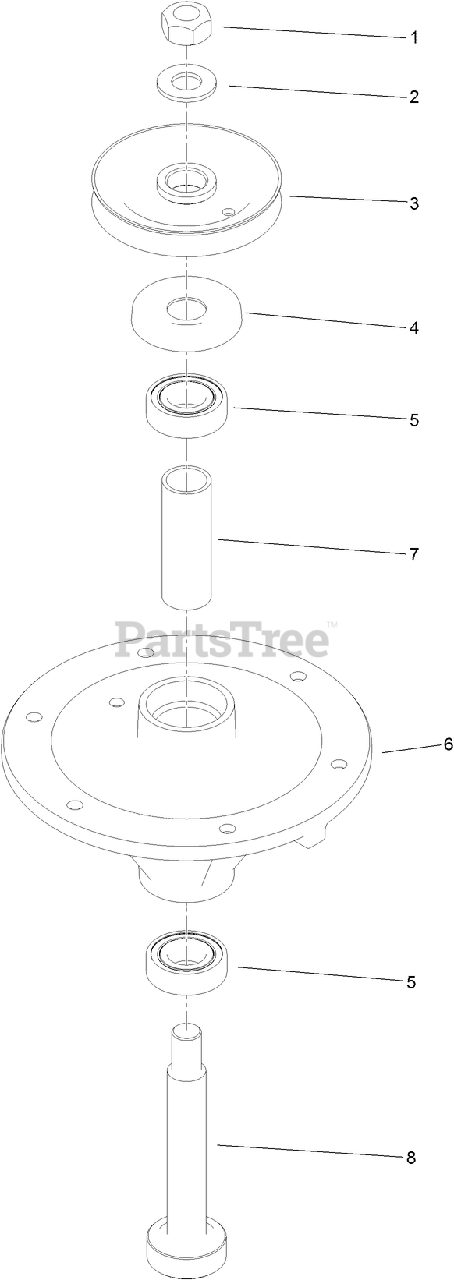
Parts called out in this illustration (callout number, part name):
1	NUT-HEX
2	WASHER
3	PULLEY ASM
4	SHIELD-BEARING
5	BEARING-BALL
6	HOUSING-SPINDLE
7	SPACER-BEARING
8	SHAFT-SPINDLE
